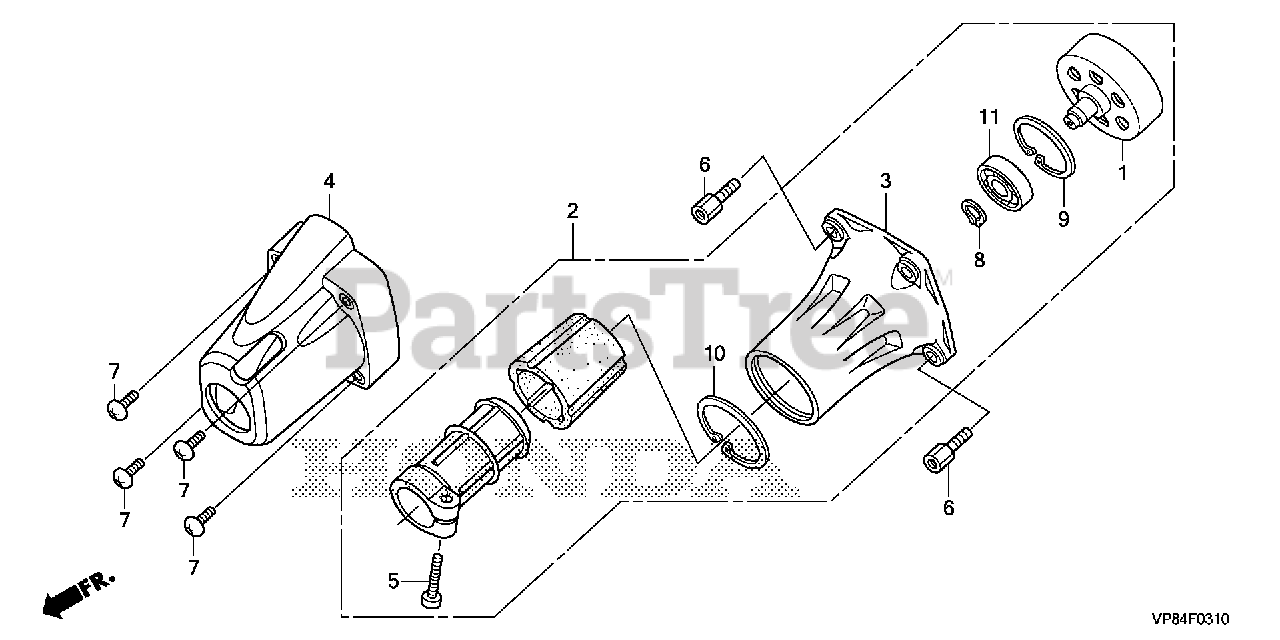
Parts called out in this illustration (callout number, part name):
1	CLUTCH OUTER
2	HOUSING ASSY., CLUTCH
3	HOUSING, CLUTCH
4	COVER, CLUTCH HOUSING
5	BOLT, TORX (5X25)
6	BOLT, SPECIAL
7	SCREW, TORUS (5X12)
8	CIRCLIP (OUTER) (12MM) Use up to Engine SN 2056819.
9	CIRCLIP (INNER) (32MM)
10	CIRCLIP (INNER) (40MM)
11	BEARING, RADIAL BALL (6201ZZ)
